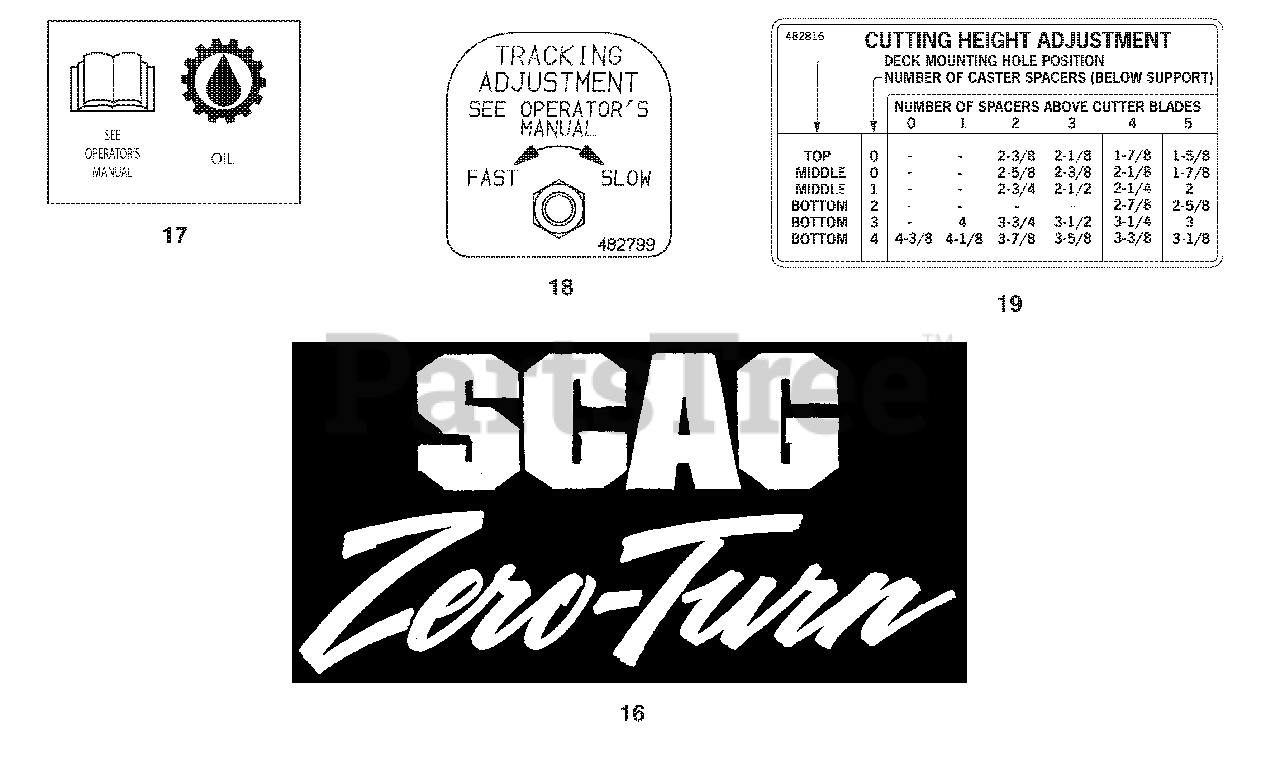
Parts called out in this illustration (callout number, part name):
16	Decal, Scag Zero Turn
17	Decal, Oil
18	Decal, Tracking Adjustment
19	Decal, Height of Cut
